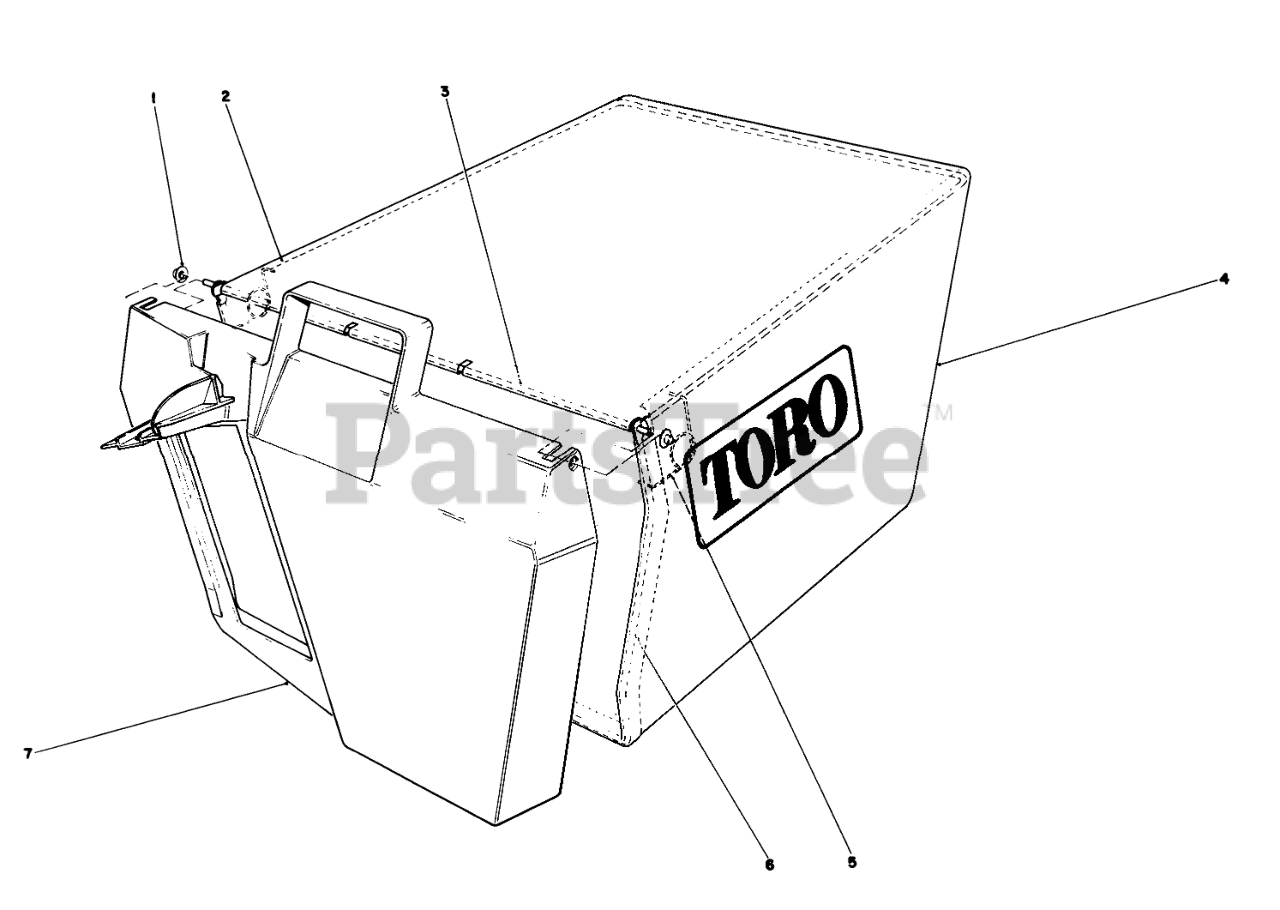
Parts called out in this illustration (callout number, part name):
1	NUT-PUSH
2	FRAME-BAG, UPPER
3	HINGE-DOOR, BAG
4	Bag
5	SPRING
6	BAG FRAME
7	Door Grass Bag
